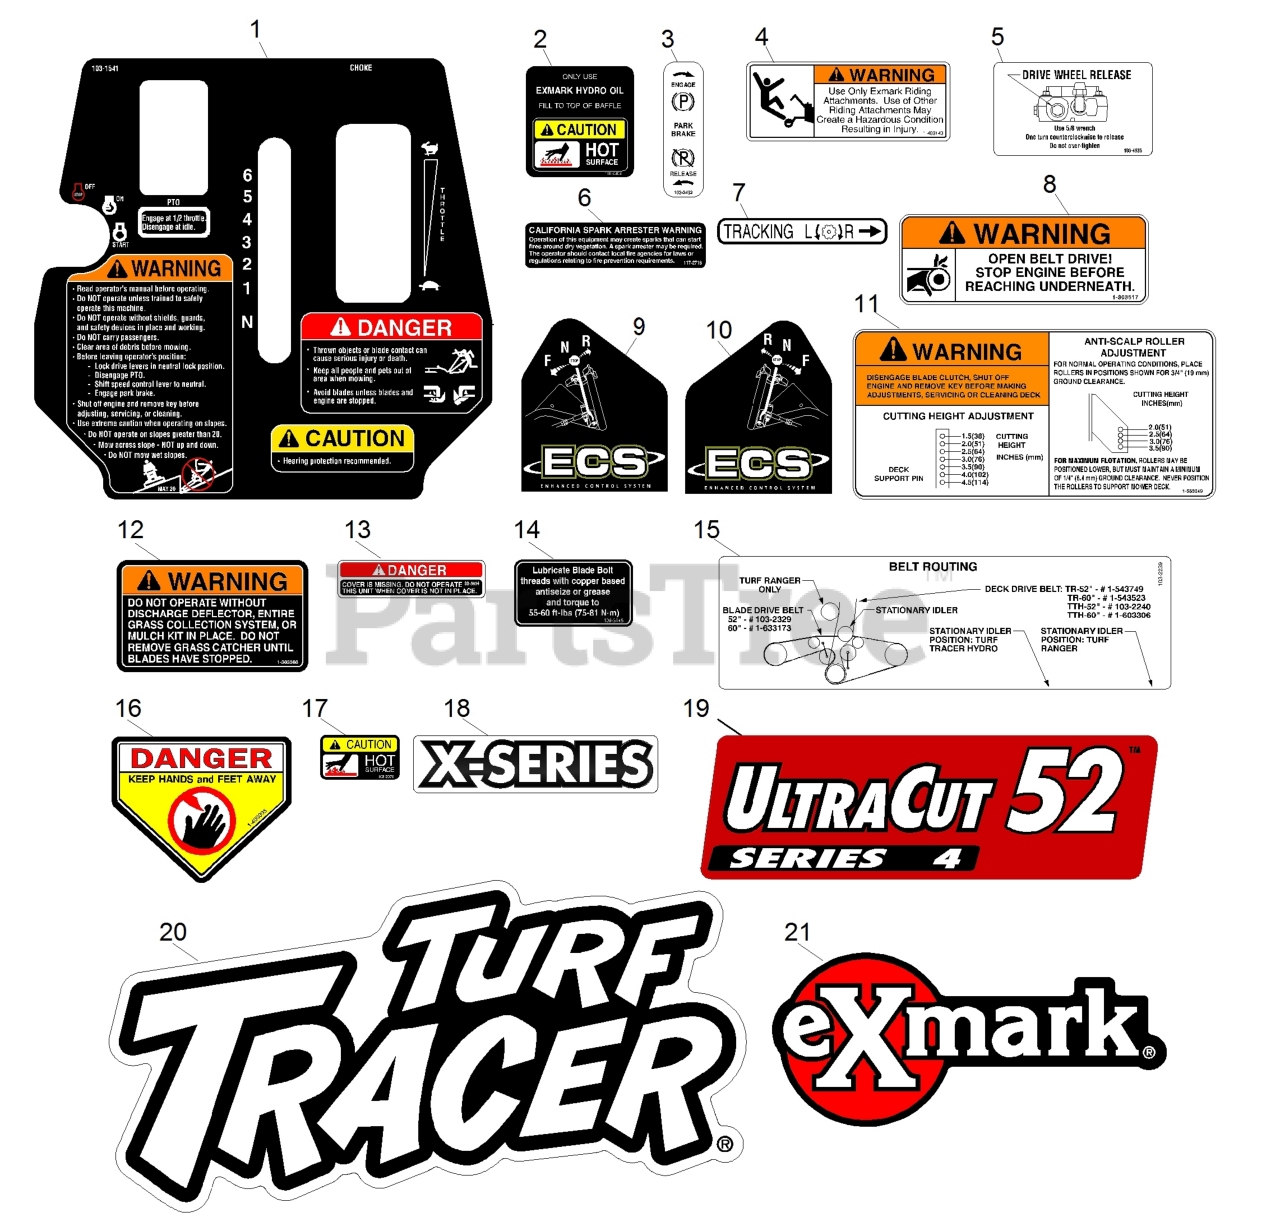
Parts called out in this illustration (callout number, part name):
1	DECAL,TTH ECS CONSOLE
2	DECAL-HYDRAULIC TANK
3	DECAL,PARKING BRAKE
4	DECAL,SULKY WARNING
5	DECAL,DRIVE RELEASE
6	DECAL-ARRESTER, SPARK
7	DECAL,TRACKING ADJUST
8	DECAL,BELT DRIVE
9	DECAL,LH ECS INSTRUCTION
10	DECAL,RH ECS INSTRUCTION
11	DECAL,ANTI SCALP
12	DECAL-WARNING, DISCHARGE
13	DECAL-COVER, MISSING
14	DECAL,BOLT TORQUE
15	DECAL,BELT ROUTING
16	DECAL-DANGER
17	DECAL-CAUTION
18	DECAL-X-SERIES
19	DECAL,ULTRACUT 52 SERIES
20	DECAL,TTH MODEL
21	DECAL,EXMARK LOGO
